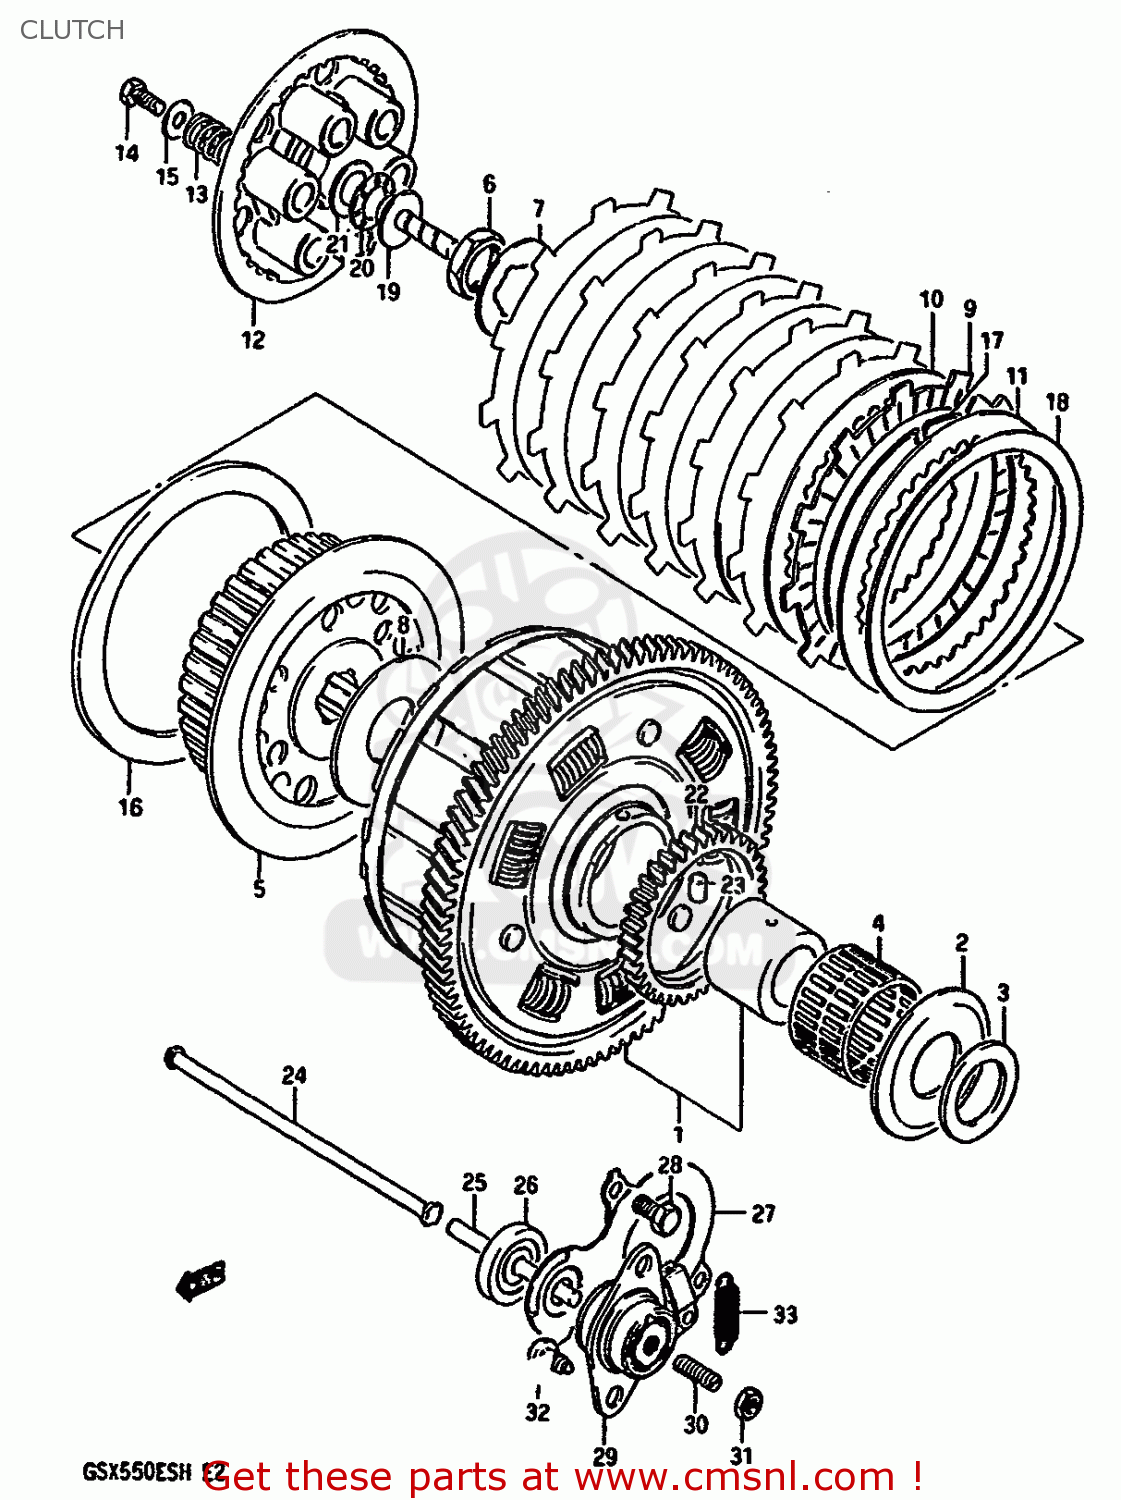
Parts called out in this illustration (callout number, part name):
1	GEAR ASSEMBLY,PRIMARY DRIVE
2	WASHER
3	WASHER
4	BEARING(40X45X32)
5	HUB,CLUTCH SLEEVE
6	NUT
7	WASHER,LOCK
8	WASHER
9	PLATE,CLUTCH DRIVE (NAS)
10	PLATE,CLUTCH DRIVEN (NAS)
11	PLATE,CLUTCH DRIVEN(T:2.0) (NAS)
12	DISC,CLUTCH PRESSURE
13	SPRING
14	BOLT
15	WASHER
16	SEAT,WAVE WASHER
17	RING,STOPPER
18	WASHER
19	PIECE,CLUTCH PUSH
20	BEARING(15X28X2)
21	WASHER
22	GEAR,OIL PUMP DRIVE
23	PIN
24	ROD,CLUTCH PUSH
25	ROD,CLUTCH PUSH,L
26	SEAL,OIL(6X34X7.5)
27	PLATE,CLUTCH PUSH ROD
28	BOLT
29	SCREW ASSY,CLUTCH RELEASE
30	SCREW(6X25)
31	NUT 6MM
32	SCREW
33	SPRING
